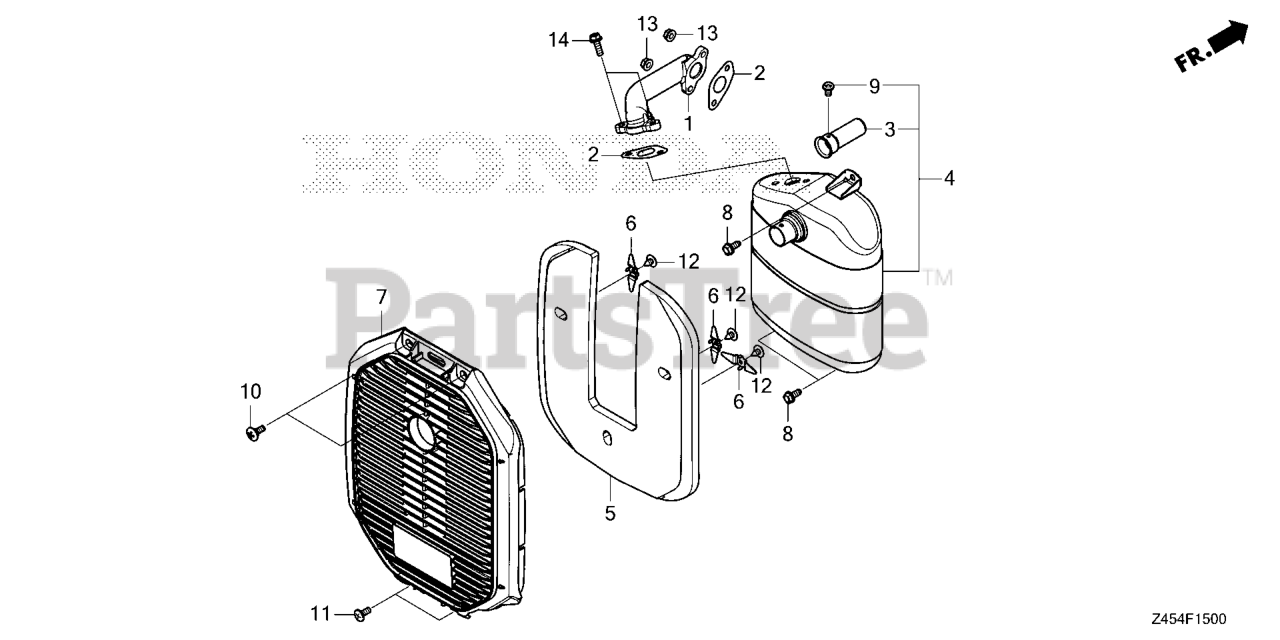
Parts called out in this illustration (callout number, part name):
2	GASKET, EX. PIPE
3	ARRESTER, SPARK
4	MUFFLER ASSY.
7	PROTR, MUFF *NH1*
8	BOLT, FLANGE (6X14)
9	SCREW, TAPPING (4X6) (TO INSTALL OPTIONAL SPARK ARRESTER)
10	SCREW, SPECIAL (6MM)
11	SCREW, SPECIAL (6X15)
12	SCREW, TAP (5X10)
13	NUT, FLANGE (6MM)
14	BOLT, FLANGE (6X18)
